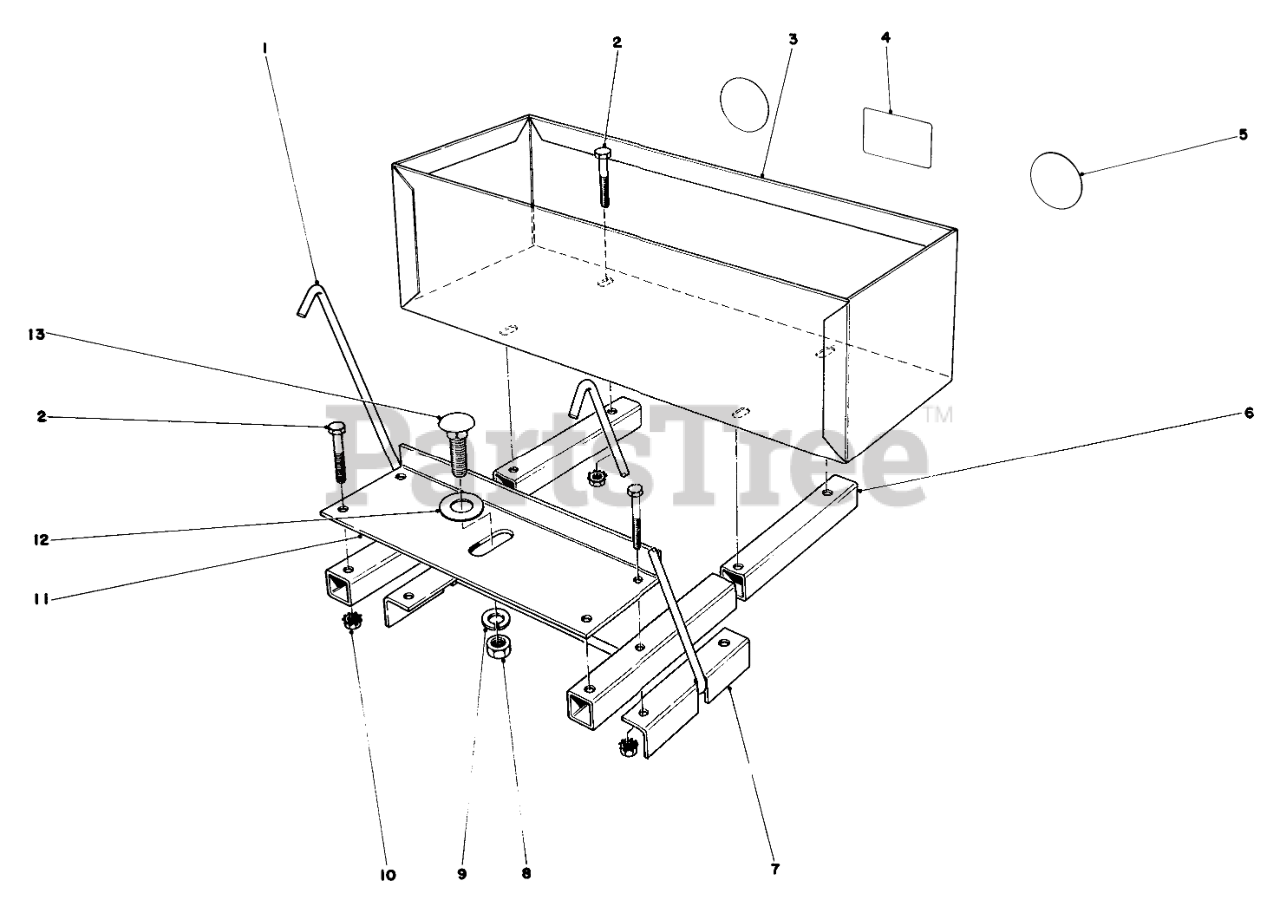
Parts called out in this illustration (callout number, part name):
1	Bracket-Support
2	SCREW-HH
3	Weight Box
4	Decal-Weight Box
5	Reflector
6	Tube-Mounting
7	Bracket-Mounting
8	NUT-HEX
9	WASHER-LOCK
10	NUT-KEPS
11	Bracket-Mounting
12	Washer
13	SCREW-CARR
